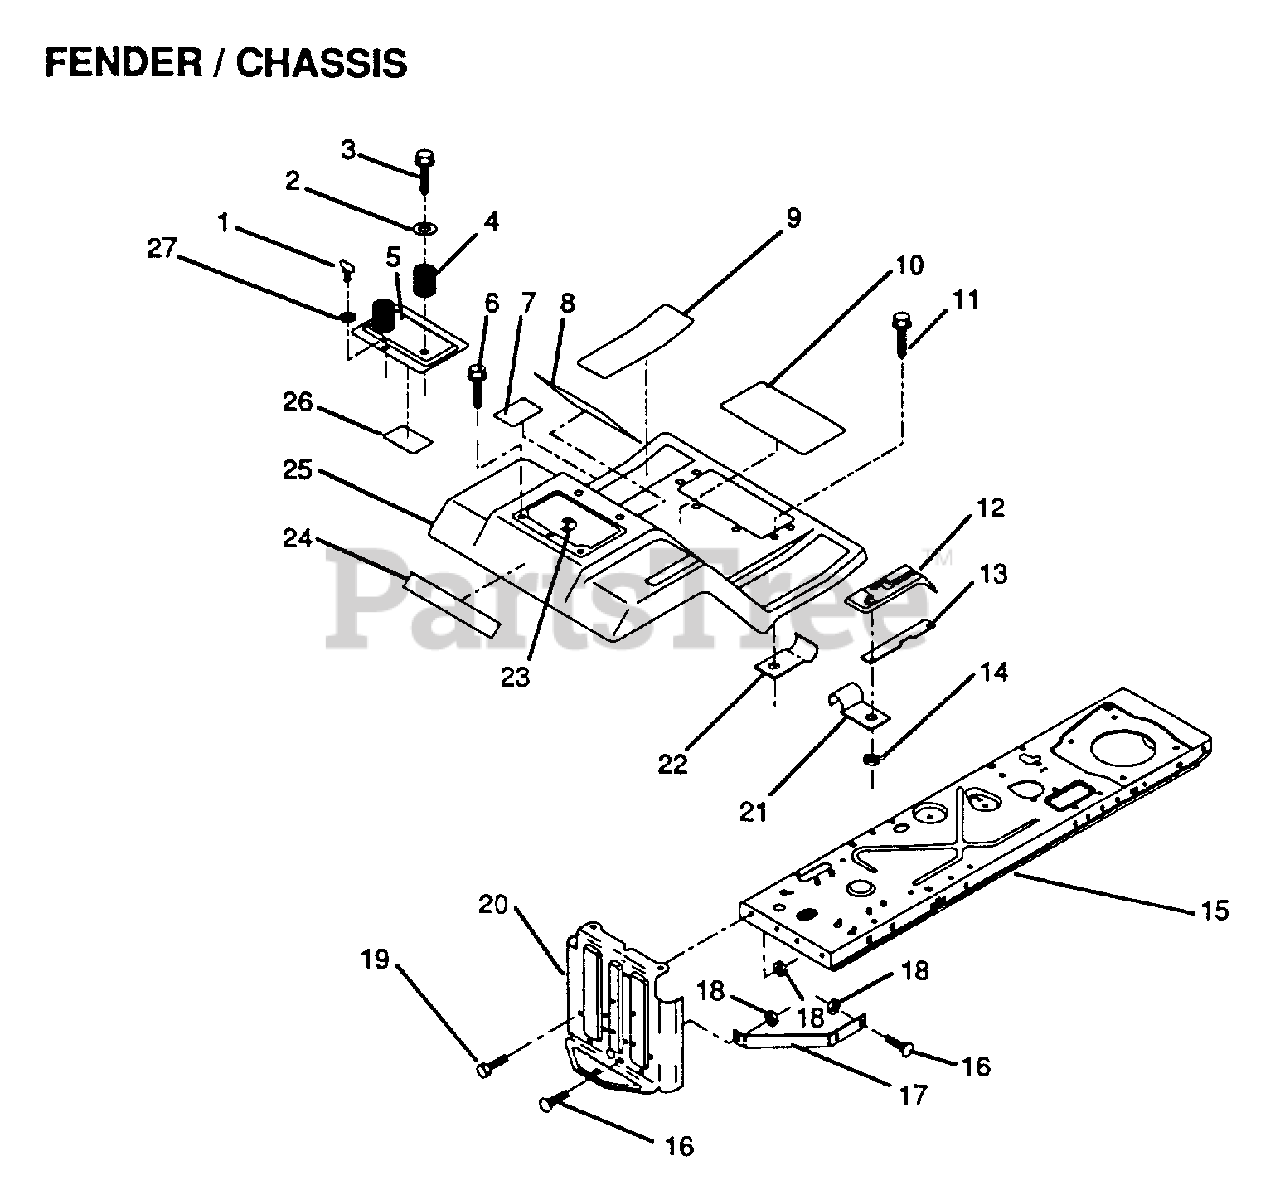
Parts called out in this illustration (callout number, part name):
1	STUD.1/4.TURN
2	WASHER
3	SCREW
4	SPRING COMPRESSIO
6	SCREW LT
7	DECAL DRIVE
8	DECAL
9	PAD FOOTREST
11	SCREW
13	"SHIFT LOCK, BAR"
14	PAL NUT
15	FRAME ASS'Y
16	BOLT
17	"BRACE,DRAWBAR "
19	BOLT
20	DRAWBAR
23	RECEPTACLE LT
26	DECAL
27	RETAINER LT
